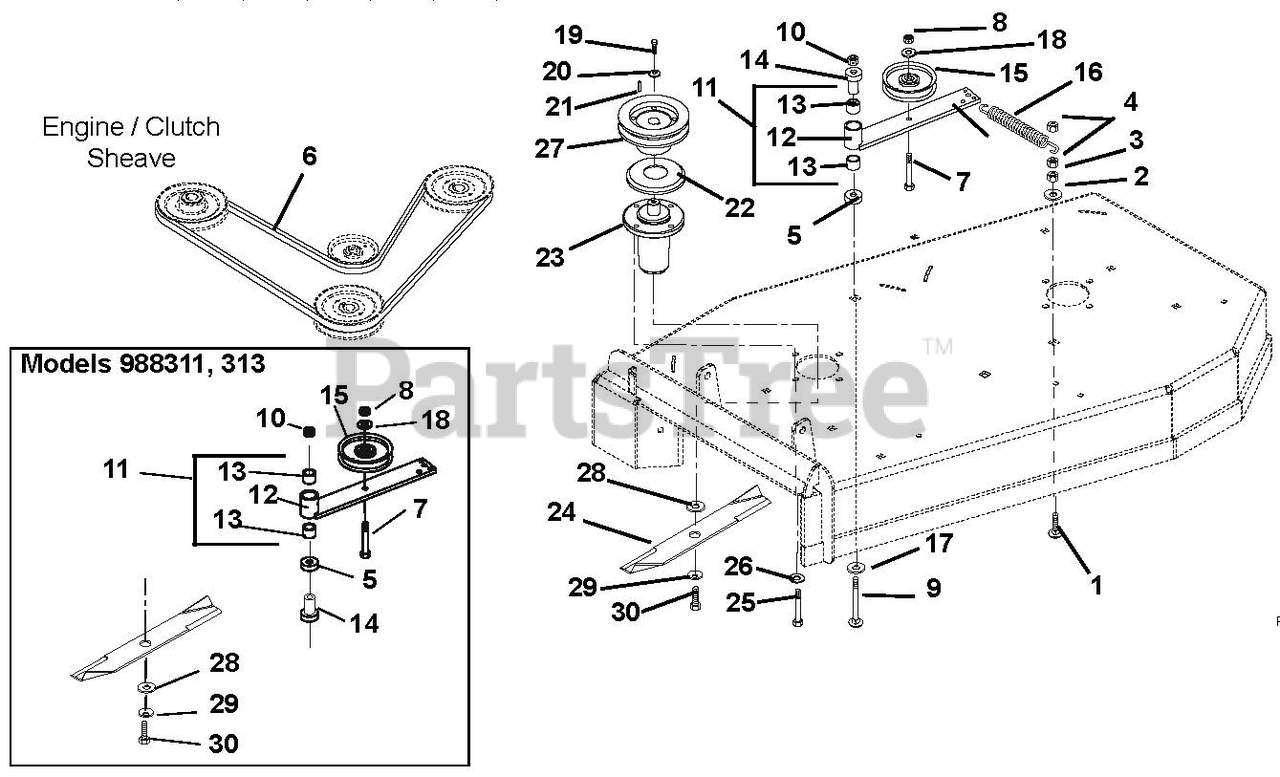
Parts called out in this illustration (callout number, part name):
1	Bolt-Round Head Square Neck .38-16 x 1.50 Grade 5
2	Washer-Locking .38 x .094 Regular
3	Nut-Hex .38-16
4	Nut-Locking-Center .38-16
5	Washer-Flat-Steel .515 x 1.625 x .25
6	V-Belt B-Section 36.70 x .650
6	V-Belt B-Section 35.47 x .650
7	Bolt-Round Head Square Neck .38-16 x 2.75 Grade 5
8	Nut-Locking-Center .38-16
9	Bolt-Round Head Square Neck .50-13 x 3.75 Grade 5
10	Nut-Locking-Center .50-13
11	Assembly, Idler Pivot Arm
12	Weldment, Idler Pivot Arm
13	Bearing, 1.00 x 1.12 x .75
14	Bearing, Pedestal Powdered Metal
15	Idler-Flat 4.00 x .38 2.00 W
16	Spring, Extension
17	Washer-Flat-Steel .755 x 1.375 x .062
18	Washer-Flat-Steel .375 x 1.125 x .065
19	Bolt-Hex .38-16 x 1.00 Grade 8
20	Washer-Cupped-Serrated .375
21	Key, Square .25 x .25 x 1.00 RC 40-50
22	Slinger-Dust
23	Assembly, Maintenance Free Spindle
24	Blade- Mower
24	Blade- Mulching
24	Blade, 32" 16.25
24	Blade- Mulching 16.12
25	Bolt-Hex .38-16 x 1.00 Grade 5
26	Washer-Locking .38 x .094 Regular
27	Pulley
28	Washer, Flat .64 x 1.81 x .250
29	Washer-Bellville .63 x 1.625 x .14
30	Bolt-Hex .62-18 x 1.75 Grade 8
